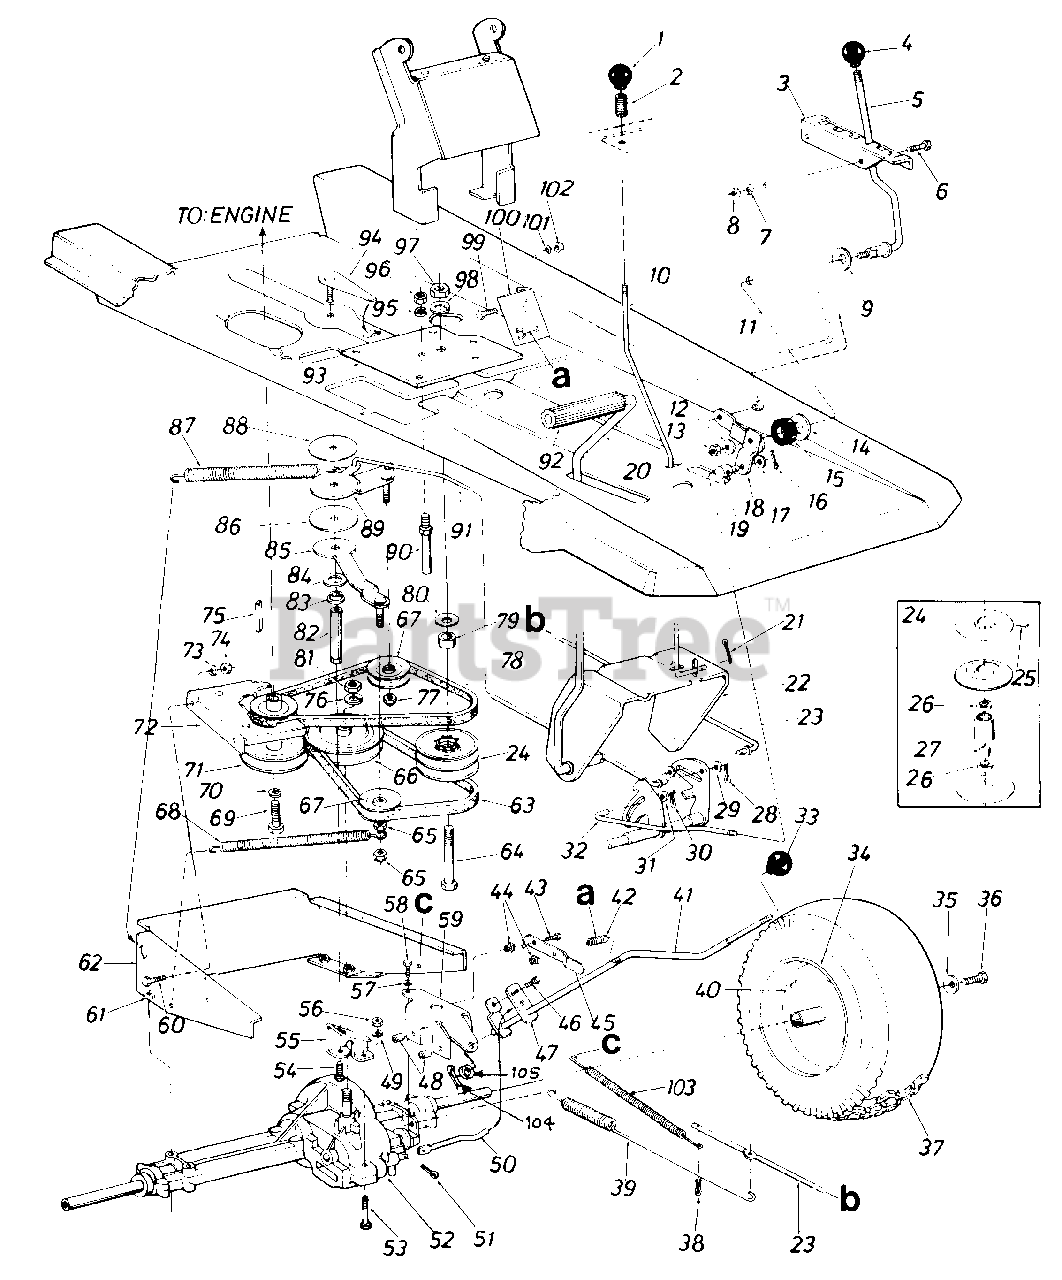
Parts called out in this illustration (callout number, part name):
1	Ball Knob 1/4-20 Thd. 1.25
2	Compression Spring
5	Speed Control Lever
6	Truss Mach. Scr. 5/16-18 x .75" Lg*
7	L-Wash. 5/16" I.D*
8	Hex Nut 5/16-18 Thd*
9	Bell-Wash. .345" I.D. x .88"
10	Brake Lockin Rod
12	Bell-Wash. .345" I.D. x .08"
13	Hex Cent. L-Nut 5/16-18 Thd.
14	Fl-Wash. .50" I.D. x 1.5" O.D.
15	Rubber Wash. .50" I.D. x 1.25" O.D.
16	Intern. Cotter Pin 1/2" Dia.
17	Fl-Wash. .34" I.D. x .68" O.D.
18	Speed Control Lever Brkt. Ass'y.
19	Ferrule Engagement
20	Clutch/Brake Pedal Ass'y.
21	Cotter Pin 3/32" Dia. x .75"*
22	Clutch/Brake Pedal Ass'y.
24	Variable Speed Pulley Ass'y.
25	Spring Pin Spir. 5/32" Dia. x .62" Lg.
26	Ball Brg. .50" I.D. x 1.38"
27	Spacer .50" I.D. x 1.00" Lg.
28	Cotter Pin 1/8" Dia. x 1.25"*
29	Fl-Wash. .34" I.D. x .60" O.D.
30	Intern. Cot-Pin 5/16" Dia.
31	Fl-Wash. .34" I.D. x .60" O.D.
32	Speed Control Rod
33	Ball Knob
35	Bell-Wash. .345" I.D. x .88"
36	Hex L-Bolt 5/16-24 x .75" Lg.
38	Cotter Pin 1/8" Dia. x 1.25"*
39	Extension Spring 17" Lg.
40	Air Valve
43	C Sink AB 0 S-Tap Scr. #8 x .50" Lg.
44	Push-in Nut #10
45	Spring Switch
46	Hex Bolt '/4-20 x .50" Lg*
47	Shift Lever Adjusting Link
48	Spacer .256" I.D. x .87" Lg.
49	L-Wash. '/4" I.D*
51	Intern. Cotter Pin
52	V Transaxle
53	Hex Bolt 1/4-20 x 1.75" Lg*
54	Hex Bolt 3/8-24 x .75" Lg*
55	Torque Rod Bracket
56	Hex Nut '/4-20 Thd*
57	L-Wash. 1/4" I.D*
58	Self-Tap Mach. Scr. Type "C1 1/4-20 x 1.37" Lg.
59	Shift Lever Support Brkt.
60	Hex Bolt 1/4-20 X 1.OO" Lg*
61	Hex Nut 5/16-18 Thd*
62	Transaxle Support Ass'y.
63	V-Belt 5/8 x 38.0" Lg.
64	Hex Bolt 1/2-13 x 4" Lg*
65	Hex Ins. L-Nut 3/8-24 Thd.
66	5/8 V-Pulley .500" I.D. x 6"
67	V-Belt Idler .38" I.D. x 3.00"
68	Ext. Spring .50" O.D. x 6.37"
69	Hex Bolt 7/16-20 x 1.00" Lg.
70	L-Wash. 7/16" I.D.
71	Engine Pulley .500" O.D. & 3.56" O.D.
72	Upper Eng. Belt Guard
73	L-Wash. 1/4" I.D*
74	Hex Nut 1/4-20 Thd*
75	Sq.-Key 1/4" X 2.00" Lg.
76	L-Wash. 1/2" I.D*
77	Hex Ins. L-Nut 3/8-24 Thd.
78	V-Belt 5/8 x 35.0" Lg.
79	Spacer .501" I.D. x .775" Lg.
80	Bell-Wash. .505" I.D. x 1.00"
81	Hex Nut 1/2-13 Thd*
83	Flange Bearing .378
84	Fl-Wash. .640" I.D. x 1.24"
85	Idler Bracket Ass'y.
86	Thrust Wash. .635" I.D.
87	Extension Spring 8.0" Lg.
88	Thrust Wash. .385" I.D.
89	Idler Bracket Ass'y. For Clutch
90	Belt Guard Pin 1/4" Dia.
92	Foot Pad
93	Mounting Bracket Variable Pulley
96	Hex Nut 1/4-20 Thd*
97	Hex Nut 1/2-13 Thd*
98	L-Wash. 1/2" I.D*
99	Hex Bolt 5/16-18 x .75" Lg*
100	Shift Lever Spring Brkt.
101	L-Wash. 5/16" I.D*
102	Hex Nut 5/16-18 Thd*
103	Extension Spring
104	Cotter Pin 3/32" Dia.
105	Flat Wash. .469" I.D. x .88" O.D.
